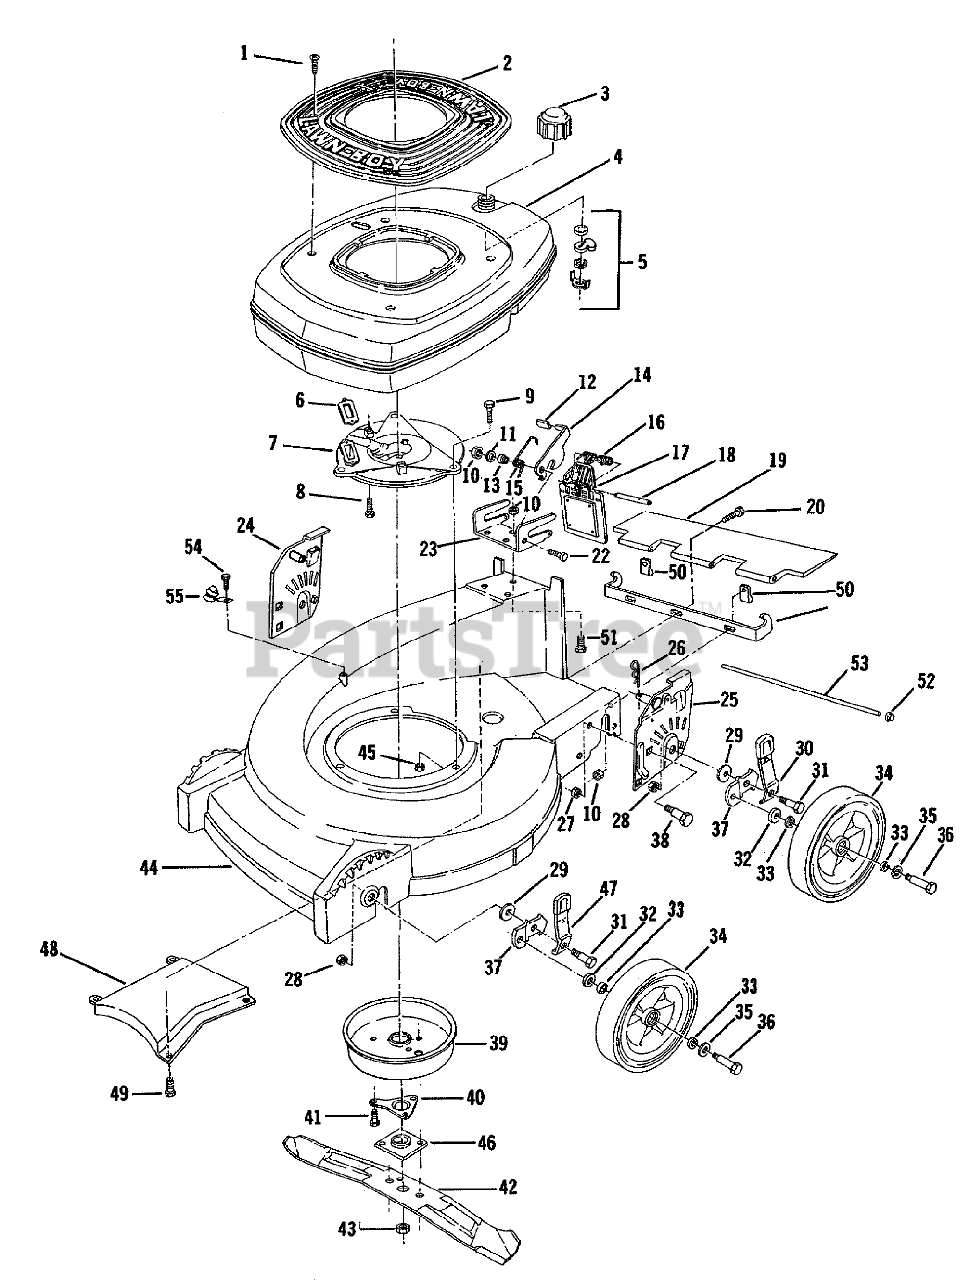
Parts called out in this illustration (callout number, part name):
1	SCREW - SELF TAPPING
3	FUEL CAP & INSERT
5	SHUT-OFF VALVE S
8	SCREW V
9	SCREW
10	LOCKNUT E
15	SPRING
16	SPRING ASOC
18	ROD (RB&W)
19	T/SHIELD SM&P
26	HAIR PIN
27	NUT-LOCK F
28	LOCKNUT
29	WASHER
32	WASHER WROUGHT
33	WASHER
35	SPACER
36	BOLT WHEEL
39	MUFFLER COVER F
40	SUPPORT F
41	SCREW
43	NUT-BLADE
45	NUT-LOCK F
46	PLATE AND COLLAR ASM
48	BAFFLE CHUTE PL
54	SCREW LAWRENCE
